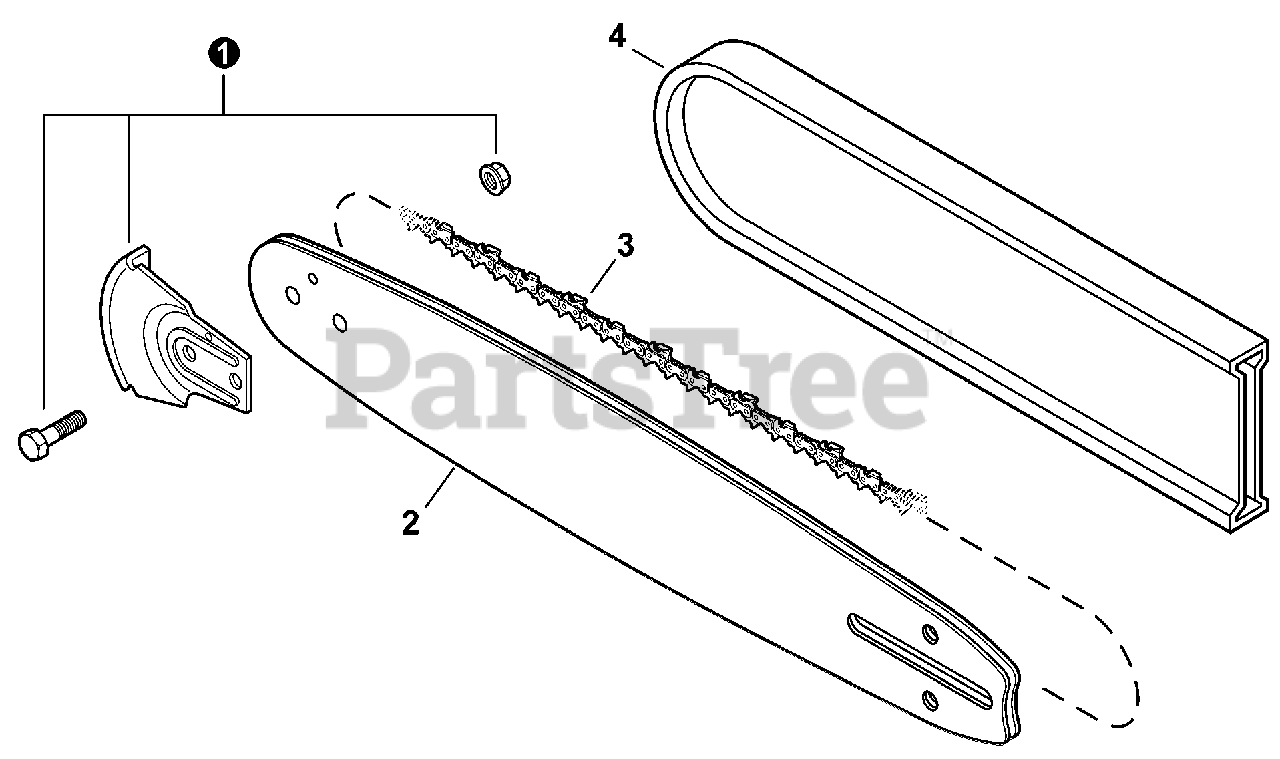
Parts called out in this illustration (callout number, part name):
1	KICK GUARD KIT
2	GUIDE BAR, 12" Micro-Lite Pro
2	GUIDE BAR, 12" Double-Guard 91
3	SAW CHAIN 12" - Micro-Lite
3	SAW CHAIN 12"
4	SCABBARD
